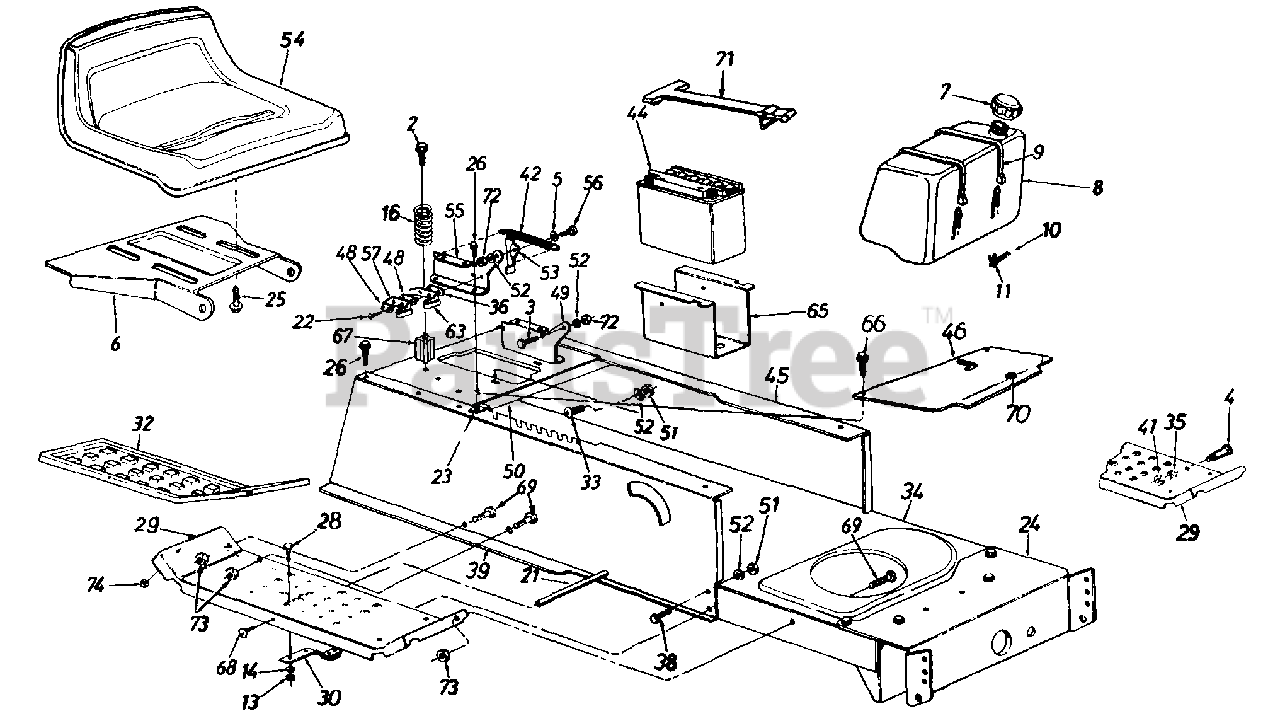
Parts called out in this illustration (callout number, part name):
2	Hex Wash. Hd. Tap Scr. 5/16-18 x 3.25" Lg.
3	Shld. Bolt .437" Dia. x .162"
4	Shld. Bolt .50" Dia. x .84"
5	Spr-Wash. .445" I.D. x .75
7	Fuel Cap
8	Fuel Tank (12.5 H.P. & Smaller)
9	Tie Strap
10	Fuel Line
11	Hose Clamp
13	Hex Nut 1/4-20 Thd.
14	L-Wash. 1/4" I.D.
16	Compression Spring
21	Running Board Rod
22	Hex Wash. Hd. AB-Tap Scr. #8 x .50" Lg.
23	Speed Nut #10Z
25	Hex Tap Scr. 3/8-16 x .62" Lg.
26	Hex Wash. Hd. AB-Tap Scr. 5/16 x .75" Lg.
28	Carriage Bolt 1/4-20 x .62"
29	Running Board (R.H. & L.H.)
30	Blade Brake Ass'y.
32	Rubber Foot Pad - L.H.
35	L-Wash. 3/8" I.D.
36	Insulator Boss Plate
38	Hex Bolt 5/16-18 x .75" Lg.
42	Extension Spring 5.31" Lg.
44	12-V Battery
52	L-Wash. 5/16" I.D.
53	Seat Lift Brkt.
54	Seat 8-7/8" High
57	Spring Switch (Seat - Outer)
63	Safety Switch (Seat - Inner)
66	Truss Mach. B-Tap Scr. #10 x .5" Lg.
67	Spring Spacer
68	Truss Mach. Scr. 5/16-18 x .75"
69	Hex Bolt 5/16-18 x .75" Lg.
70	Snap Bushing
71	Battery Retainer Strap
72	Hex Nut 5/16-18 Thd.
73	Hex Sems Nut 5/16-18 Thd.
74	Hex Sems Nut 1/4-20 Thd.
